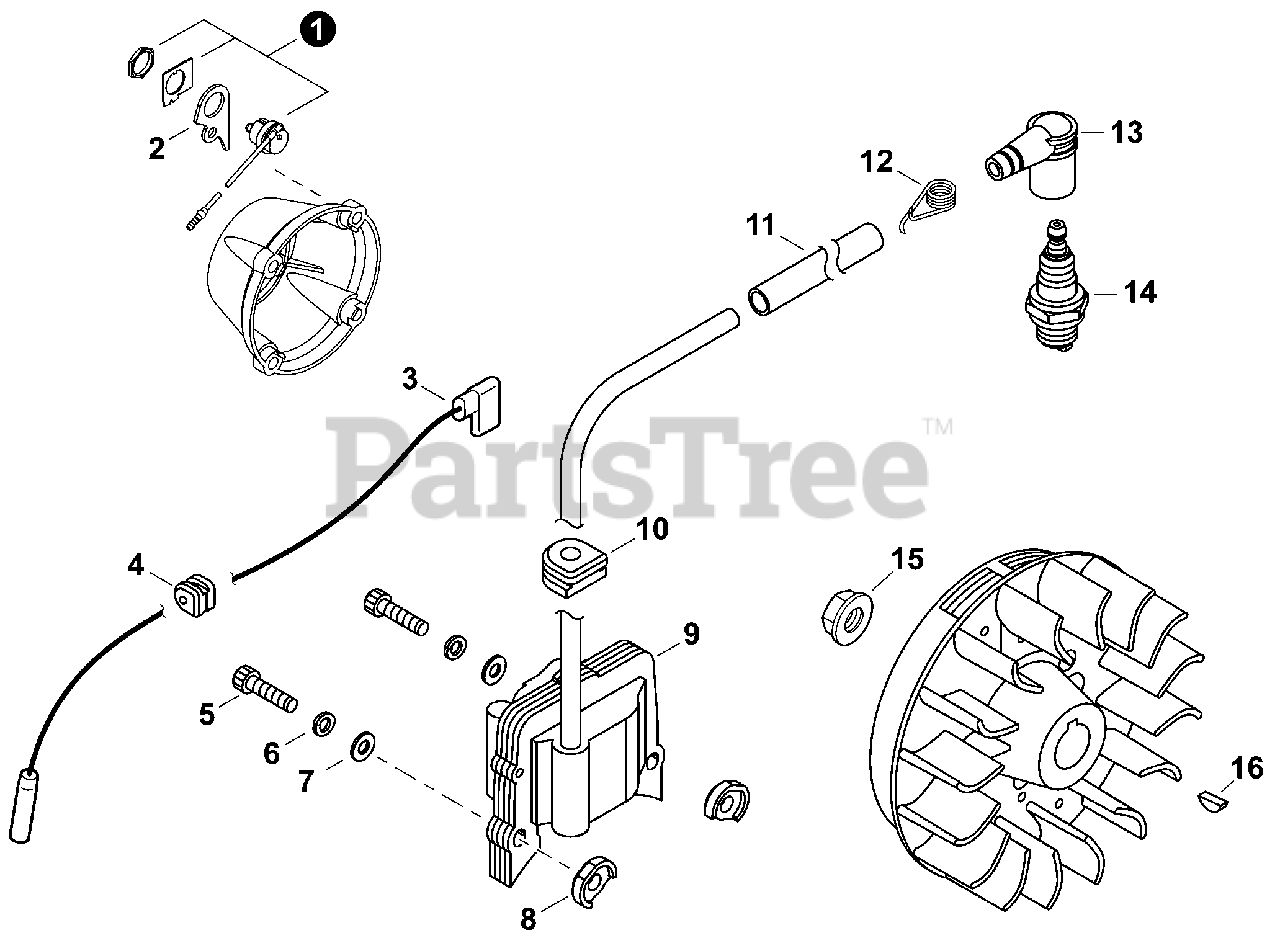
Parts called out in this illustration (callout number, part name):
1	SWITCH, ON-OFF
2	BRACKET
3	LEAD - IGNITION
4	GROMMET, LEAD
5	BOLT M4×24
6	WASHER, SPRING 4 MM
7	WASHER 4.3×9.6×0.8
8	COLLAR 4
9	COIL, IGNITION
10	GROMMET
11	TUBE, INSULATOR
12	TERMINAL, SPARK PLUG
13	CAP, SPARK PLUG
14	SPARK PLUG - CJ8
15	NUT, FLANGE M10
16	KEY, WOODRUFF 3×10
